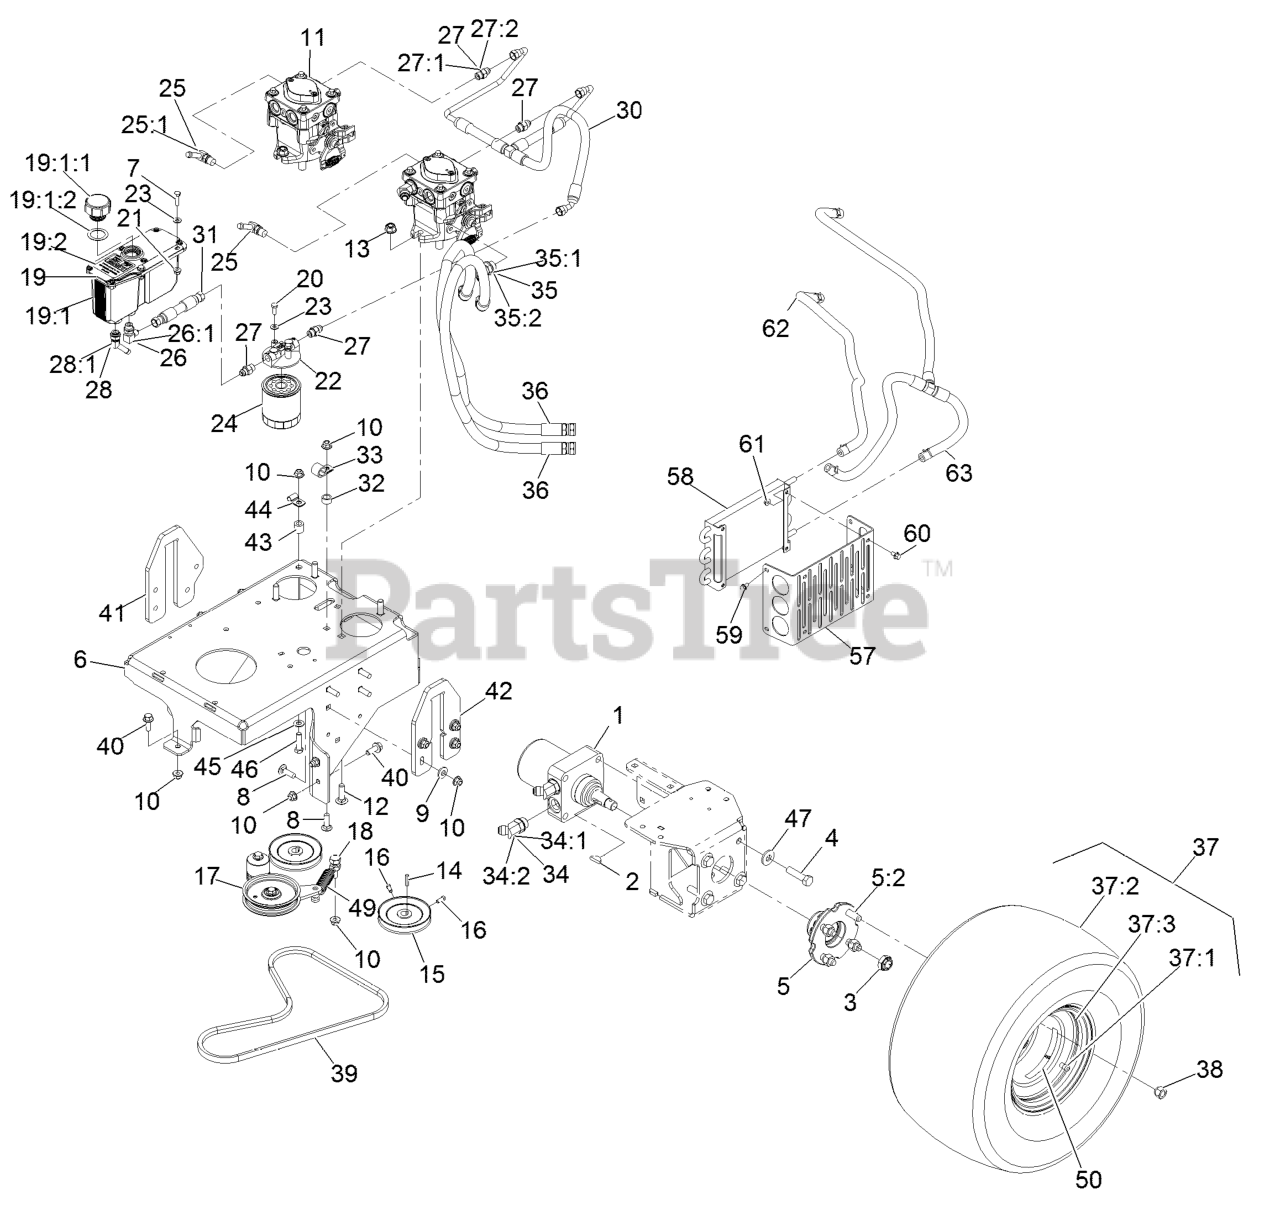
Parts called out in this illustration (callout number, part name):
1	MOTOR-WHEEL
2	KEY-WOODRUFF
3	NUT-LOCK
4	SCREW-HH
5	WHEEL HUB ASM
5:2	STUD-TYPE, DRIVE
6	BASE-ENGINE
7	SCREW-HH
8	BOLT-CARR
9	WASHER-BELLEVILLE
10	NUT-HF, NI
11	PUMP - HYDRAULIC
12	SCREW-HH
13	NUT-HF, NI
15	PULLEY-PUMP
16	SCREW-SET
17	PUMP IDLER ASM
19	RESERVOIR ASM
19:1	Reservoir-Hyd
19:1:1	Cap-Reservoir, HYD
19:1:2	GASKET-CAP
19:2	DECAL-HYDRAULIC TANK
20	SCREW-HH
21	NUT-HHF
22	HEAD-FILTER
23	WASHER-FLAT
24	FILTER-25 MICRON, BI-DIRE
25	FITTING-ELBOW, 90
25:1	O-RING
26	FITTING-ELBOW, 90 DEG
27	FITTING-STRAIGHT
28	FITTING-BARBED, 45 DEG
28:1	O-RING
30	HOSE ASSEMBLY - CHARGE
31	HYD HOSE ASM
32	SPACER-WHEEL
33	CLIP-LOOM
34	FITTING-HYD, 45 DEG
35	FITTING-HYD, 45 DEG
36	HYD HOSE ASM
37	WHEEL/TIRE ASM
37:1	RIM-8 INCH
37:3	Stem-Valve
38	NUT-LUG
39	BELT-V, LOWER PTO
40	SCREW-HHF 3/8-16 X 1
41	PLATE-LIFT, RH
42	PLATE, LIFT LH
44	CLIP-TUBE
45	WASHER-FLAT
46	SCREW-HH
47	WASHER-SPRING
49	SPRING-EXTENSION
57	BRACKET, COOLER MOUNTING
59	SCREW-HWH
60	SCREW-HHF
61	NUT-KEPS
62	HOSE-HYDRAULIC
